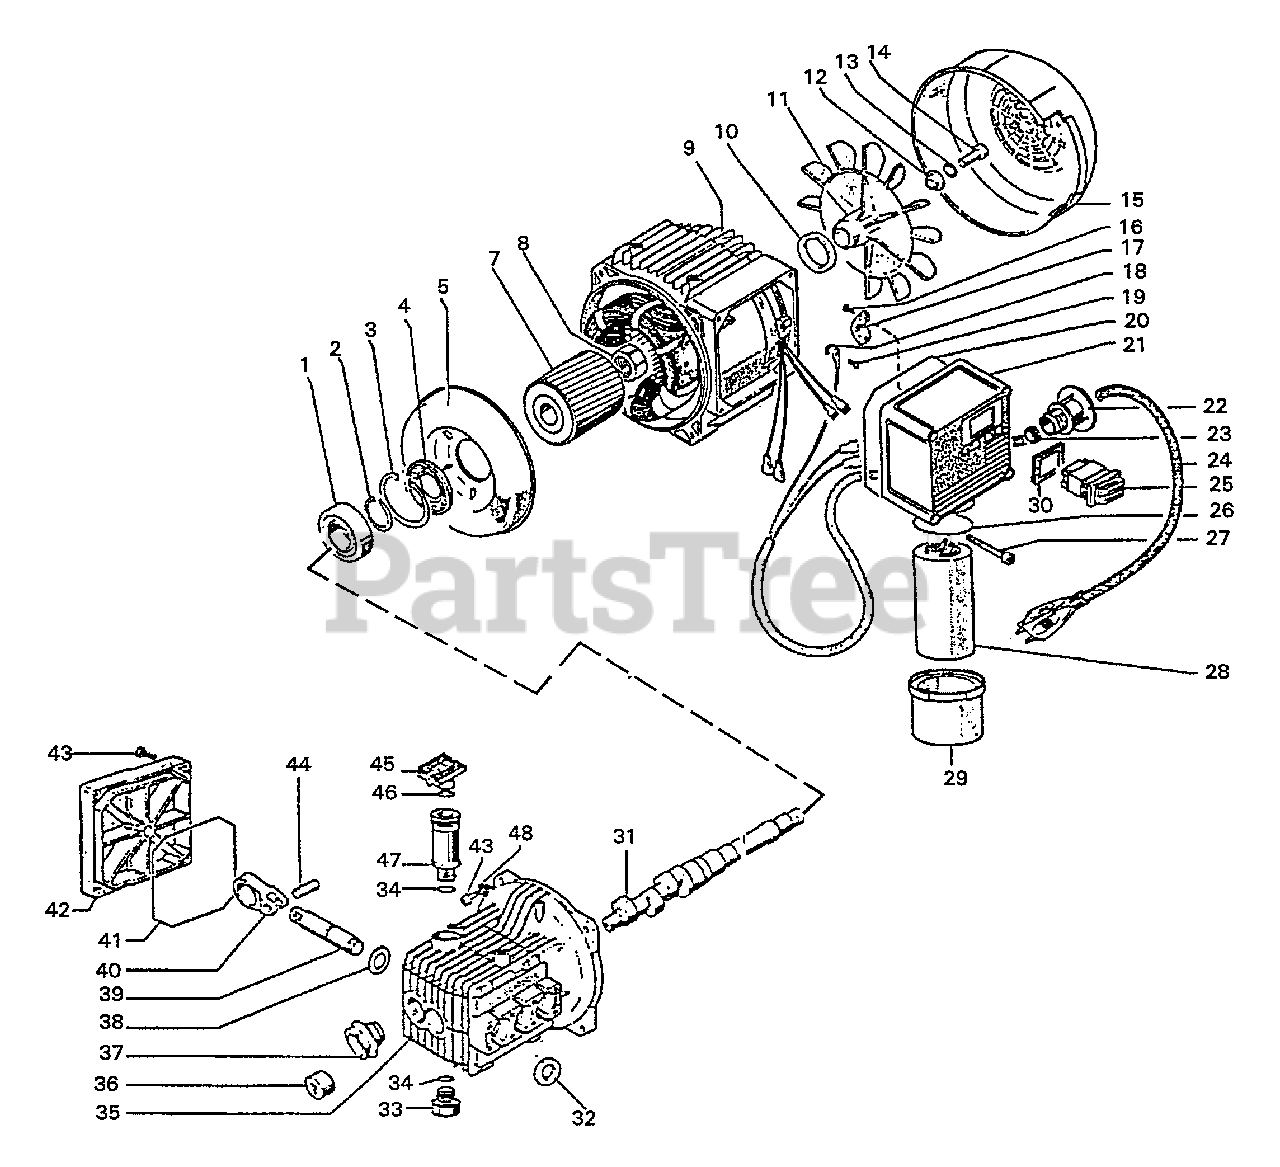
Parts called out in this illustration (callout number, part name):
1	BEARING, BALL
2	RING, RETAINING
3	RING, RETAINING
4	SEAL, OIL
7	ROTOR
8	NUT - 22
9	STATOR
10	SEAL
11	FAN
12	SPACER, FAN
13	WASHER
14	SCREW - 8X20
15	COVER, FAN
16	SCREW
17	CLAMP
18	WASHER
19	SCREW - 5X12
20	O-RING
21	COVER, SWITCH
22	HOLDER, CABLE
23	GROMMET, CORD GRIP
24	CABLE ASSY
25	SWITCH, IGNITION
26	O-RING, 1.925 X .103
27	SCREW - 5X65
28	CONDENSER
29	COVER, CAPACITOR
30	GASKET, SWITCH
31	CRANKSHAFT ASSY
32	OIL SEAL KIT
33	PLUG
34	O-RING
35	CRANKCASE
36	BEARING, NEEDLE
37	INDICATOR - OIL LEVEL
38	WASHER
39	PISTON - STAINLESS
40	ROD, CONNECTING
41	GASKET, COVER
42	COVER, CRANKCASE
43	SCREW - 6X25
44	PIN, CONNECTING ROD
45	COVER, OIL FILL
46	O-RING
47	SPACER, DIPSTICK
48	LOCKWASHER - 6
